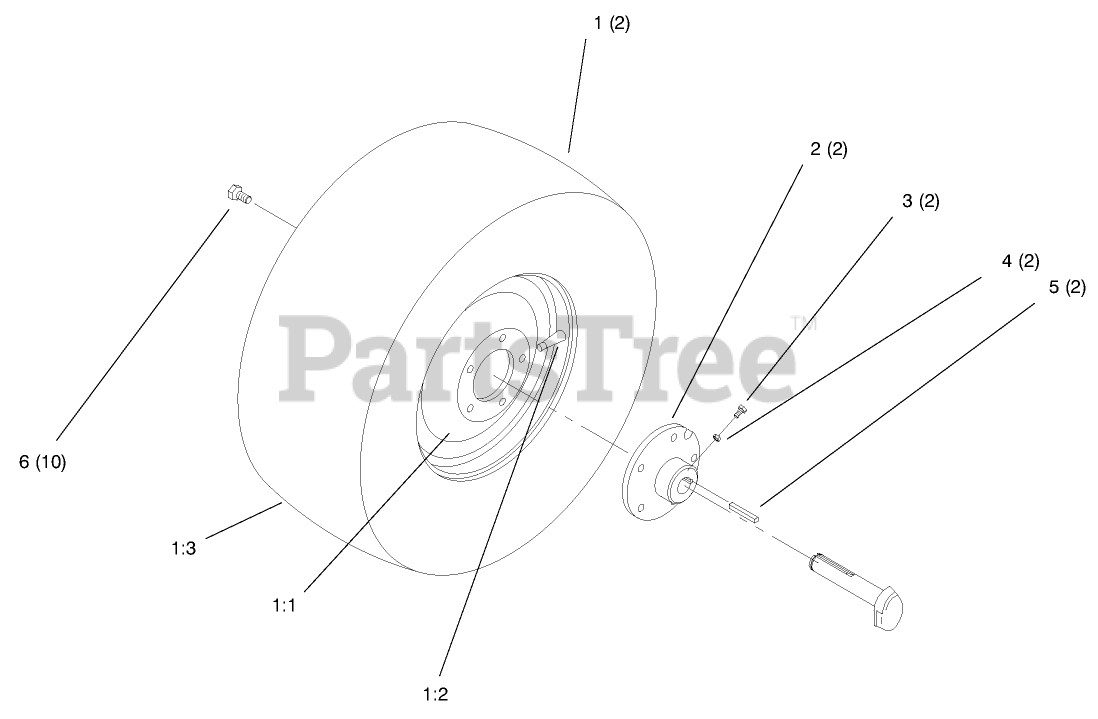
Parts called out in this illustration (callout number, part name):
1	Wheel AND Tire ASM
1:1	WHEEL
1:2	VALVE
2	HUB-WHEEL
3	SCREW-SET, SQH
4	NUT-JAM
5	KEY-SQUARE
6	BOLT-LUG
